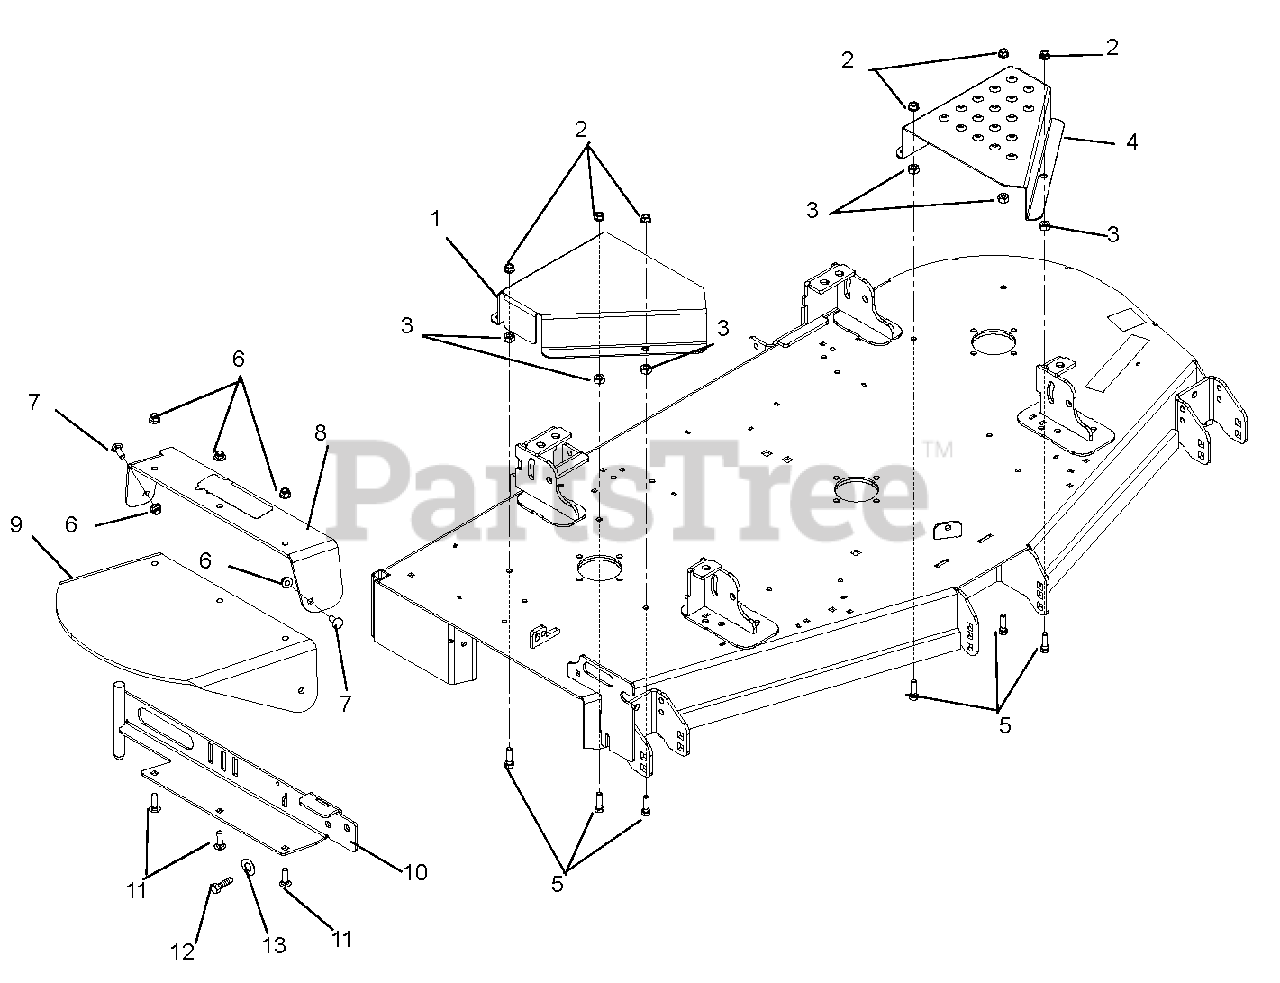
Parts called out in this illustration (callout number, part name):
1	Cover, Right Hand Deck Belt, 52
2	Nut-Spin Lock-Flange .375-16
3	Nut-Heavy Hex .38-16
4	Cover, Left Hand Deck Belt, 52
5	Bolt, Hex .38-16 x 1.25 Grade 5
6	Nut, Locking-Nylon-Flange .38-16
7	Bolt, Round Head Square Neck .38-16 x 1.00 Grade 5
8	Support, Rubber Discharge Chute
9	Chute, Rubber Discharge
10	Discharge Chute Mounting Weldment
11	Bolt, Round Head Square Neck .38-16 x 1.25 Grade 5
12	Bolt-Hex .50-13X1.00 Grade 5
13	Washer, Locking .50 x .125 Regular
